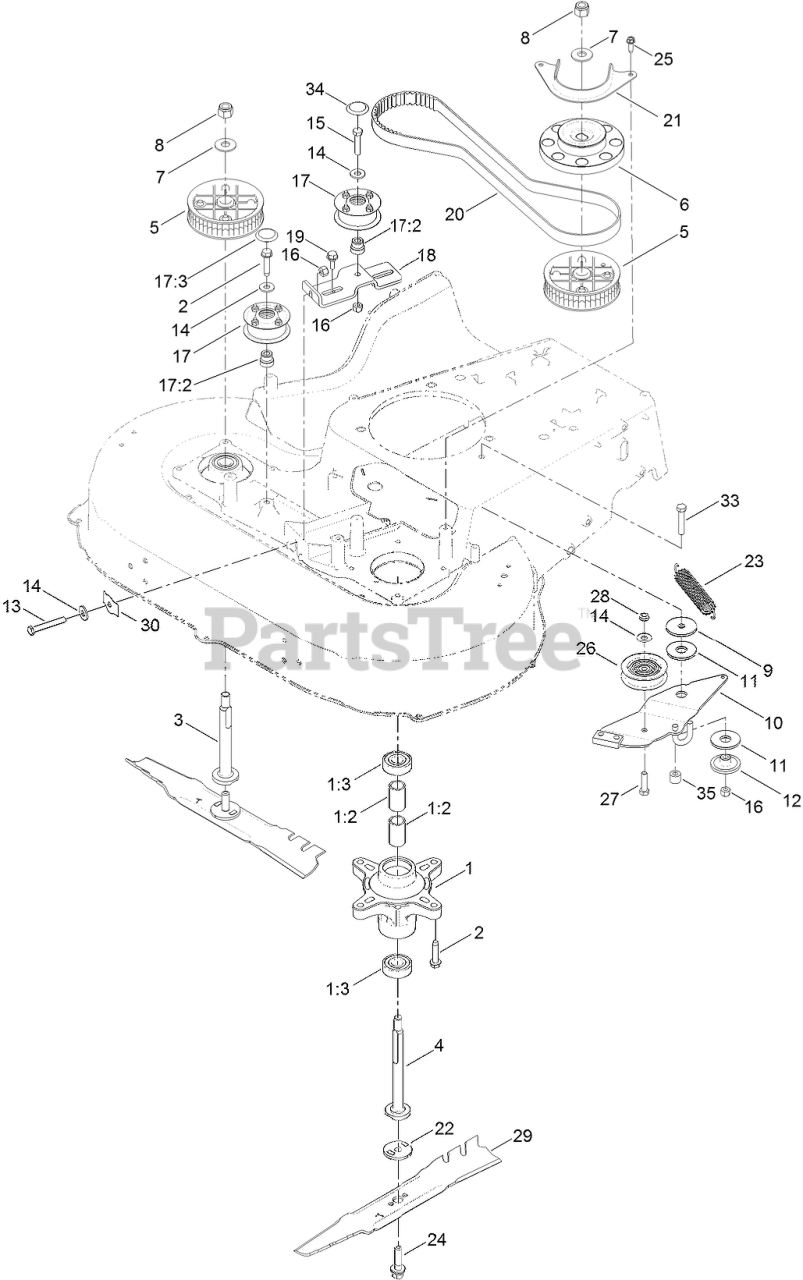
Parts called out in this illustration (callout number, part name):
1	SPINDLE ASM
1:2	SPACER
1:3	BEARING-BALL
3	SHAFT-SPINDLE
4	SHAFT-SPINDLE
5	SPROCKET
6	PULLEY-BRAKE, SPINDLE
7	WASHER-SPRING
8	NUT-HEX
9	WASHER-REBOUND
10	BRAKE ARM ASM
11	WASHER-FRICTION, COMPOSITE
12	SPACER
13	BOLT-TAP, HH
14	WASHER-FLAT
15	SCREW-HH
16	NUT-LOCK, NI
17	PULLEY KIT
17:2	ADAPTER-BORE
17:3	PLUG-CAP
18	BRACKET-IDLER
19	SCREW-SHOULDER, HHF
20	BELT-SYNCHRONOUS
21	GUIDE-BELT, SPINDLE
22	ADAPTER-BLADE
23	SPRING-EXTENSION, BRAKE
24	BOLT-BLADE
25	SCREW-HWHTF
26	PULLEY-IDLER
27	SCREW-HH
28	NUT-LOCK, NI
29	BLADE-ROTARY
30	SPRING-FLAT
33	SCREW-HH
34	PLUG-CAP
35	HOSE-COOLANT
